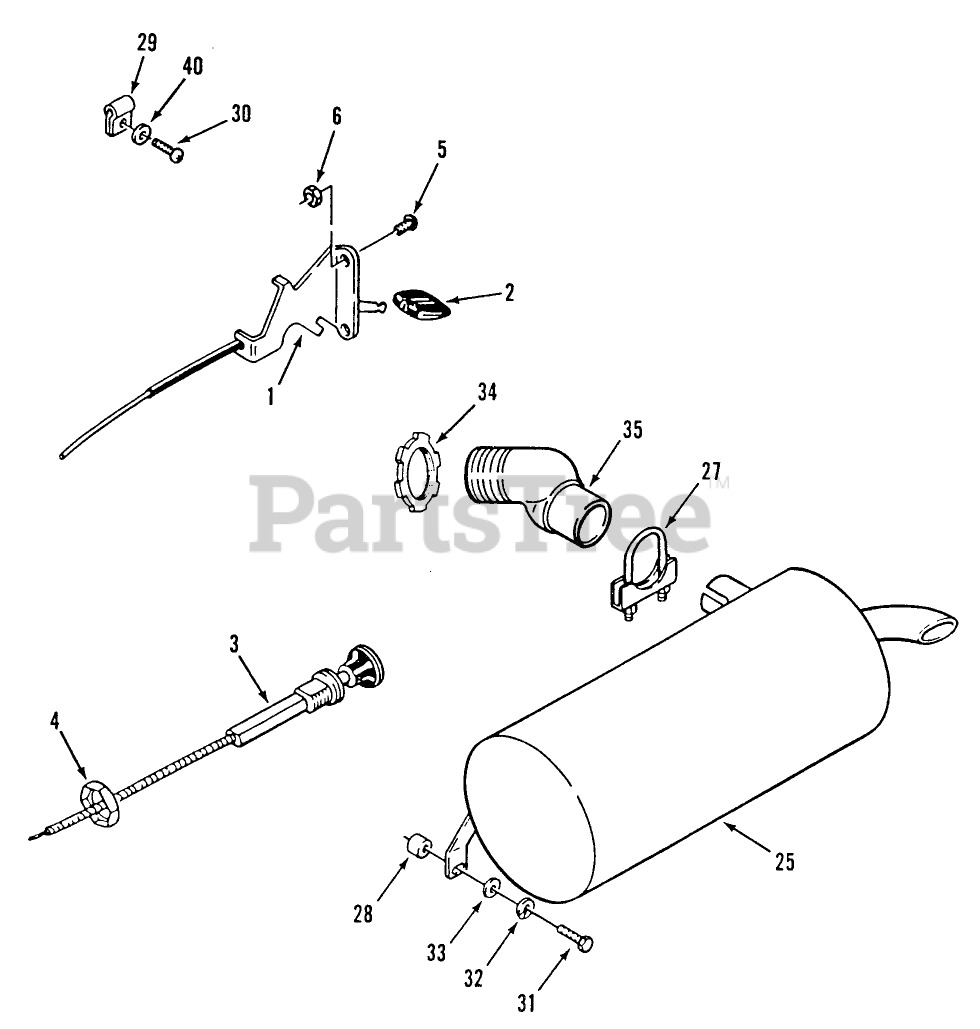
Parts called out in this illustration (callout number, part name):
2	KNOB-THROTTLE
3	CONTROL CHOKE
4	NUT-HEX PALNUT
5	SCREW-PPH
28	SPACER
29	KOHLER 48-154-01
30	Hex Wash. Hd. Screw 1/4-20 x 7/16 (vendor nr. X-67-83)
33	WASHER 5/16 SAE
34	KOHLER AC-1536
35	KOHLER47-054-01
40	KOHLER X-25-72
